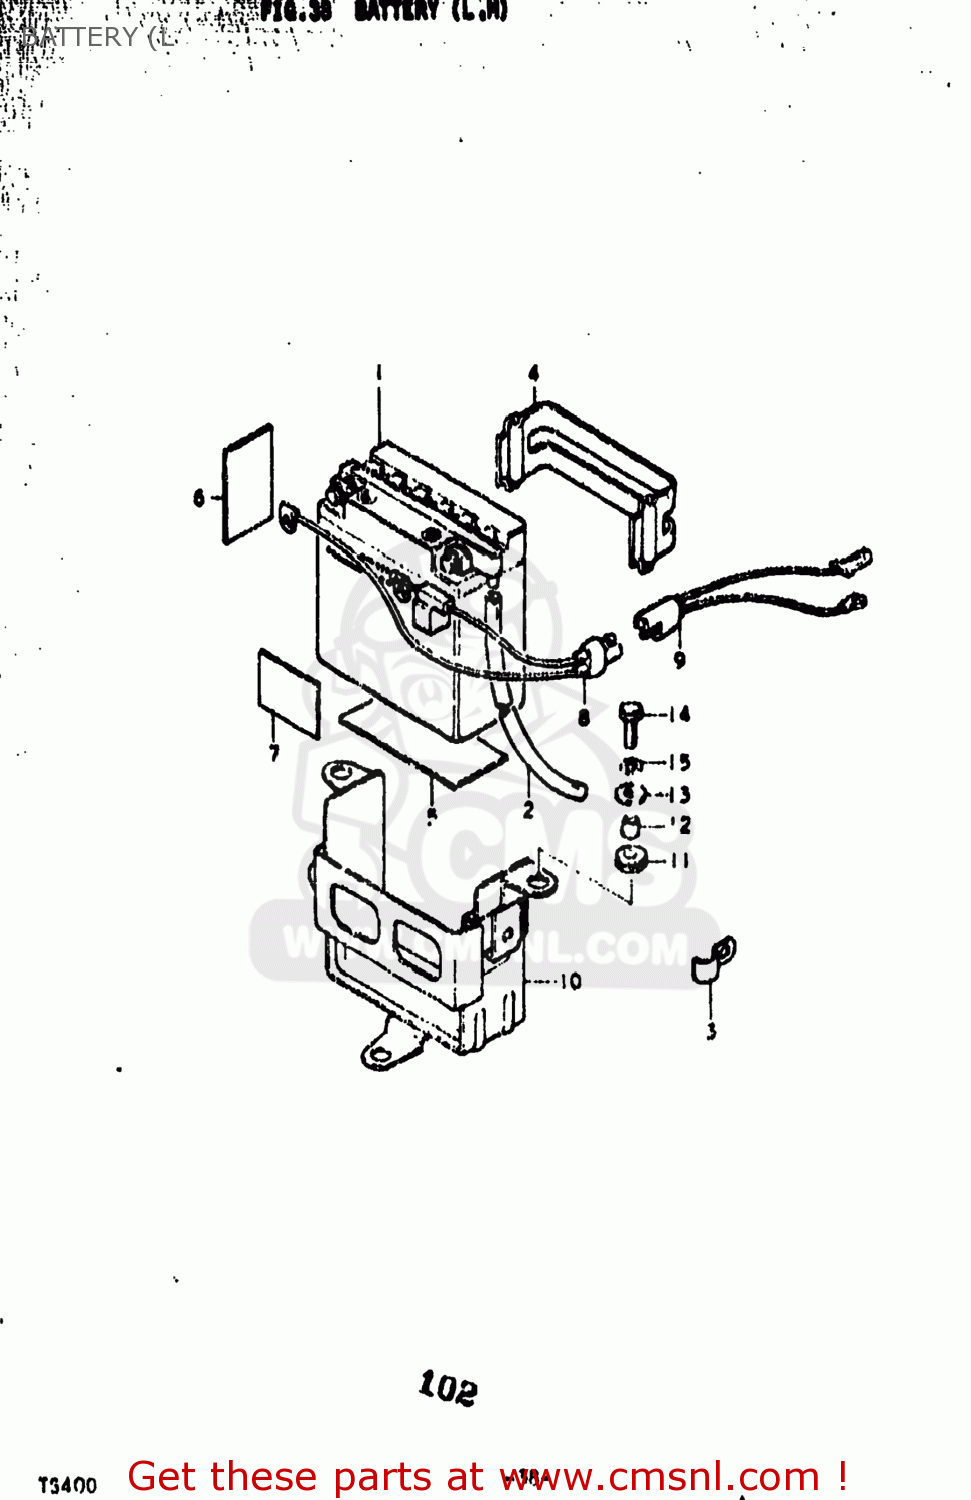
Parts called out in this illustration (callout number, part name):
1	BATTERY ASSEMBLY
2	HOSE,BATTERY EXHAUST
3	CLAMP
4	BAND
5	PROTECTOR,BATTERY
6	CUSHION,BATTERY
7	PROTECTOR,BATTERY
8	CABLE,BATTERY
9	WIRE,BATTERY LEAD
10	HOLDER,BATTERY
11	CUSHION
12	SPACER (7X9X7)
13	WASHER (6.5X20X1.2)
14	BOLT
15	LOCK WASHER
